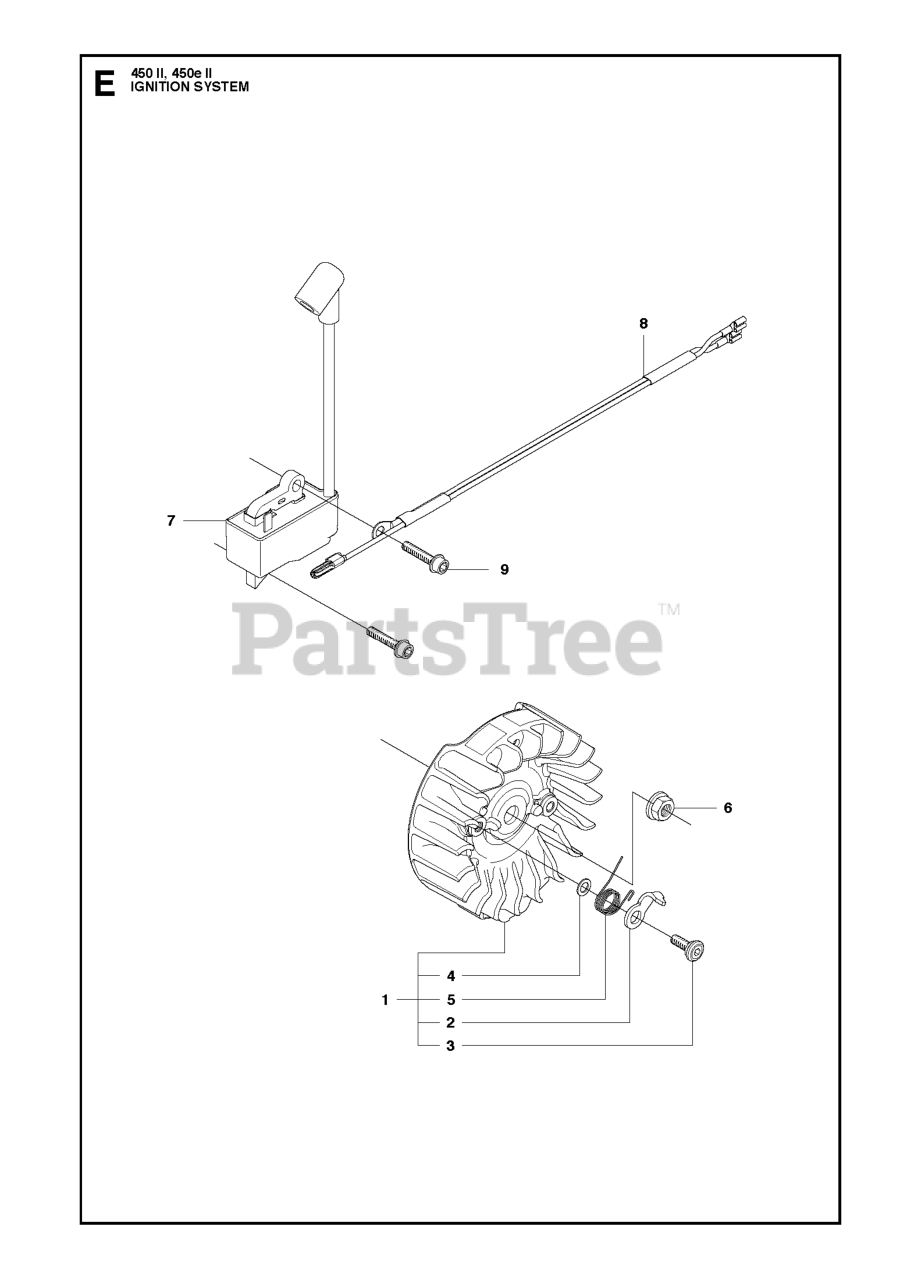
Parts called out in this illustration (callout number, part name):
1	FLYWHEEL ASSY
6	NUT W/ WASHER
7	RP IGNITION MODULE
8	WIRING ASSY
